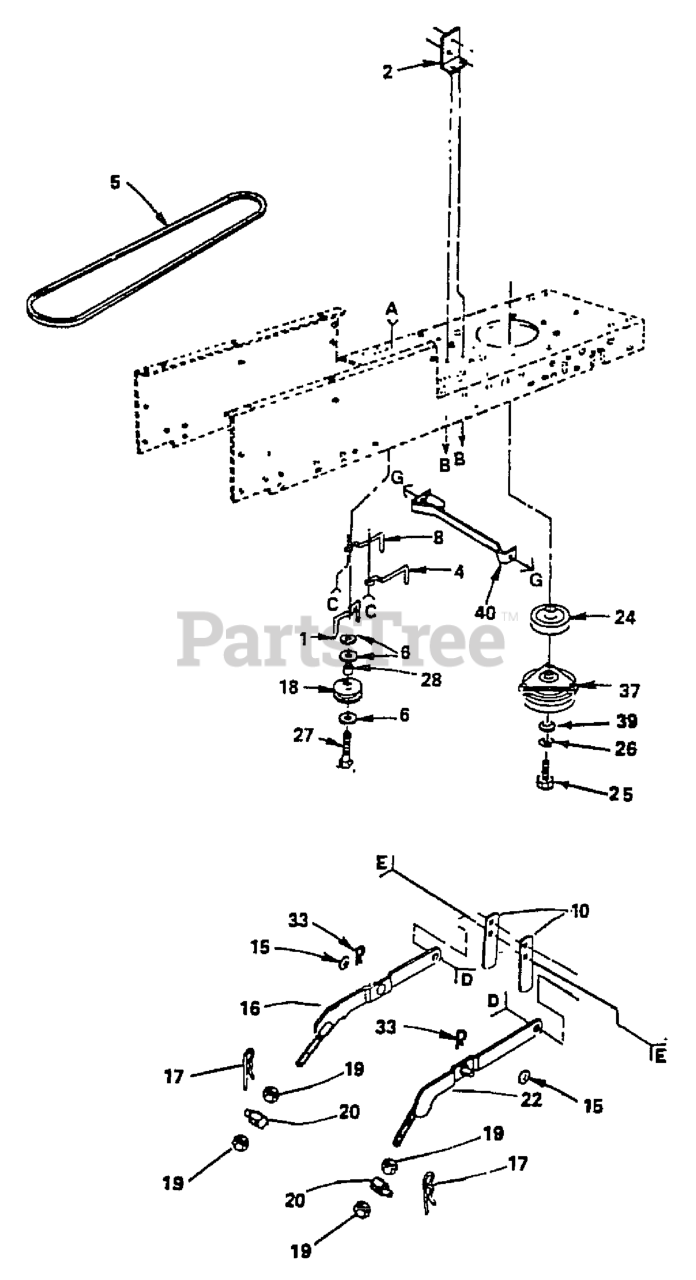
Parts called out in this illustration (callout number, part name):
1	BELT KEEPER LT NLA
2	BRACKET LT
4	KEEPER,BLT ENG LT
5	BELT.GROUND.DRIVE
6	WASHER
8	KEEPER BELT ENGLH
15	WASHER T
16	LH SUSP ARM ASM
17	SPRING H
18	PULLEY.IDLER.FLAT
19	NUT 1/2 X 13
20	TRUNION LFT LR LT
22	RH SUSP ARM ASM
24	ENGINE PULLEY
25	Bolt, Hex 7/16-20 x 4 Grade B
26	LOCKWASHER
27	BOLT
33	SPRING TI
37	CLUTCH ELEC HYT
40	KIT RETAINER YTH
